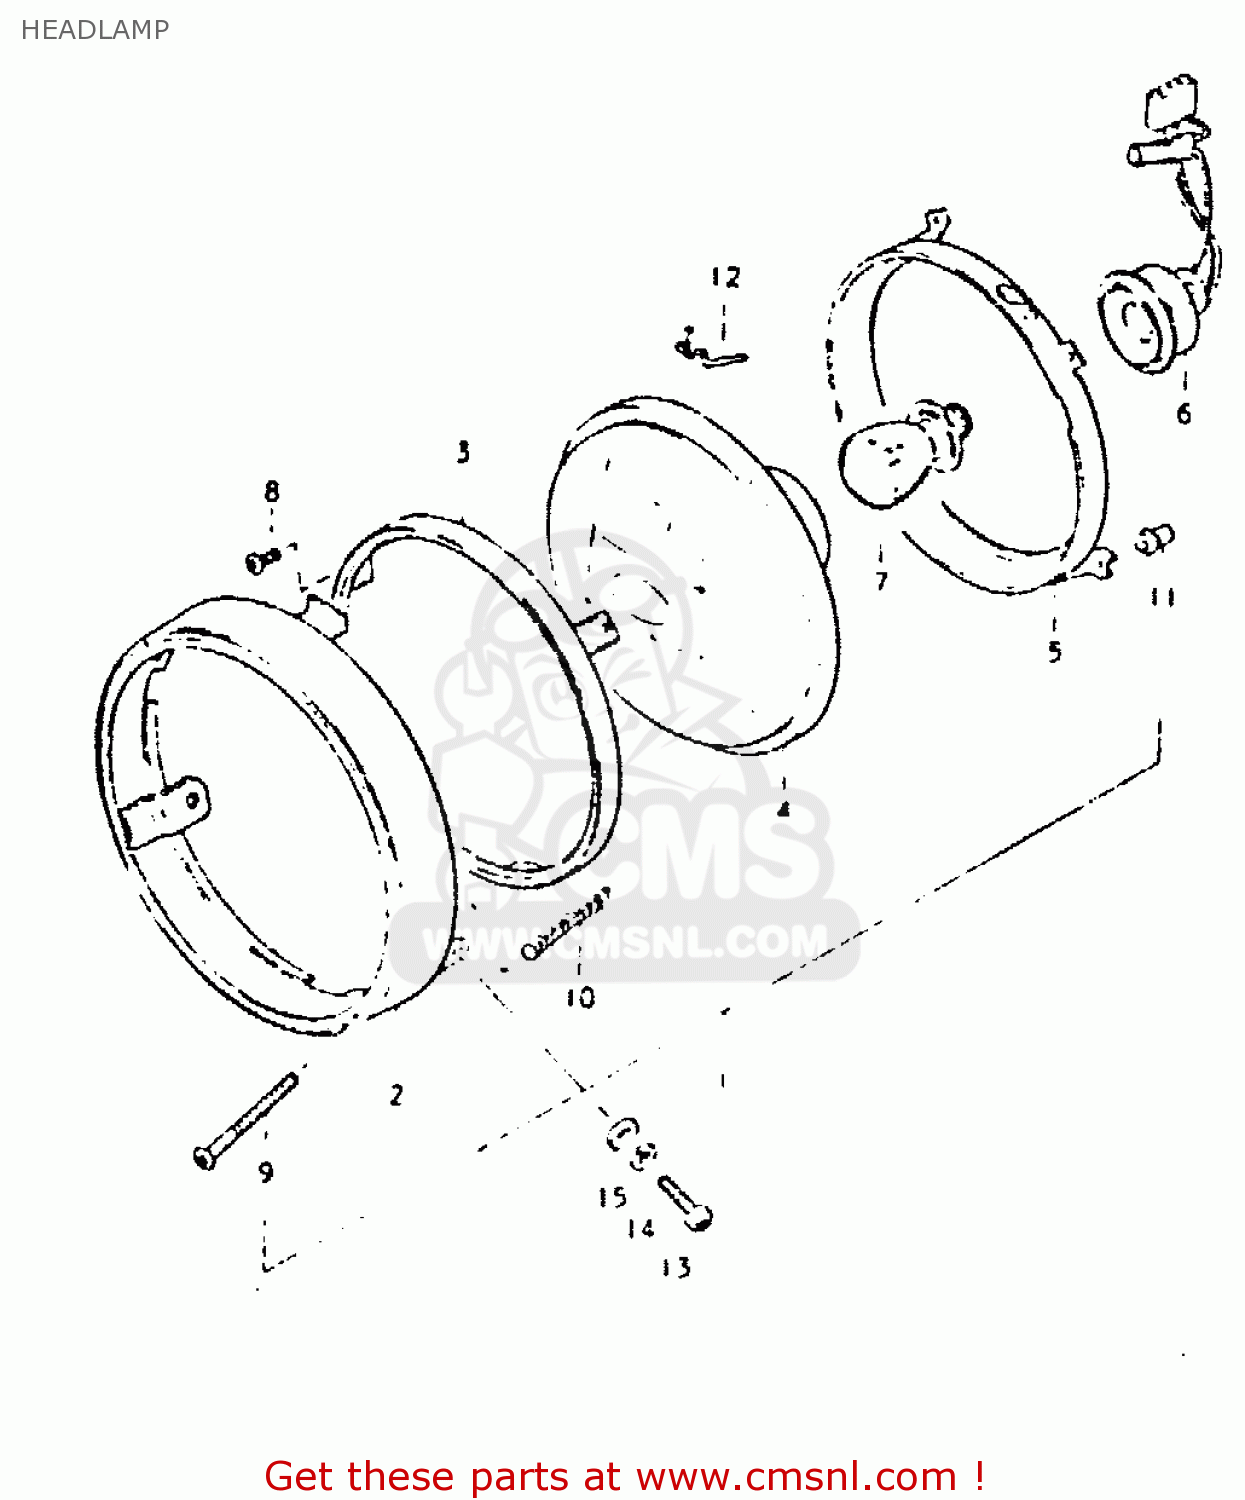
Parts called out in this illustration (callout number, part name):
1	HEADLAMP ASSY
2	RIM
3	RETAINER,HEADLAMP
4	UINT
5	RING, MOUNTING
6	SOCKET
7	BULB(6V,35/35W)
8	SCREW
9	SCREW,HEADLAMP ADJUST
10	SPRING,ADJUSTING
11	NUT,HEADLAMP ADJUSTER
12	SPRING,HEADLAMP UNIT
13	SCREW
14	LOCK WASHER
15	WASHER
